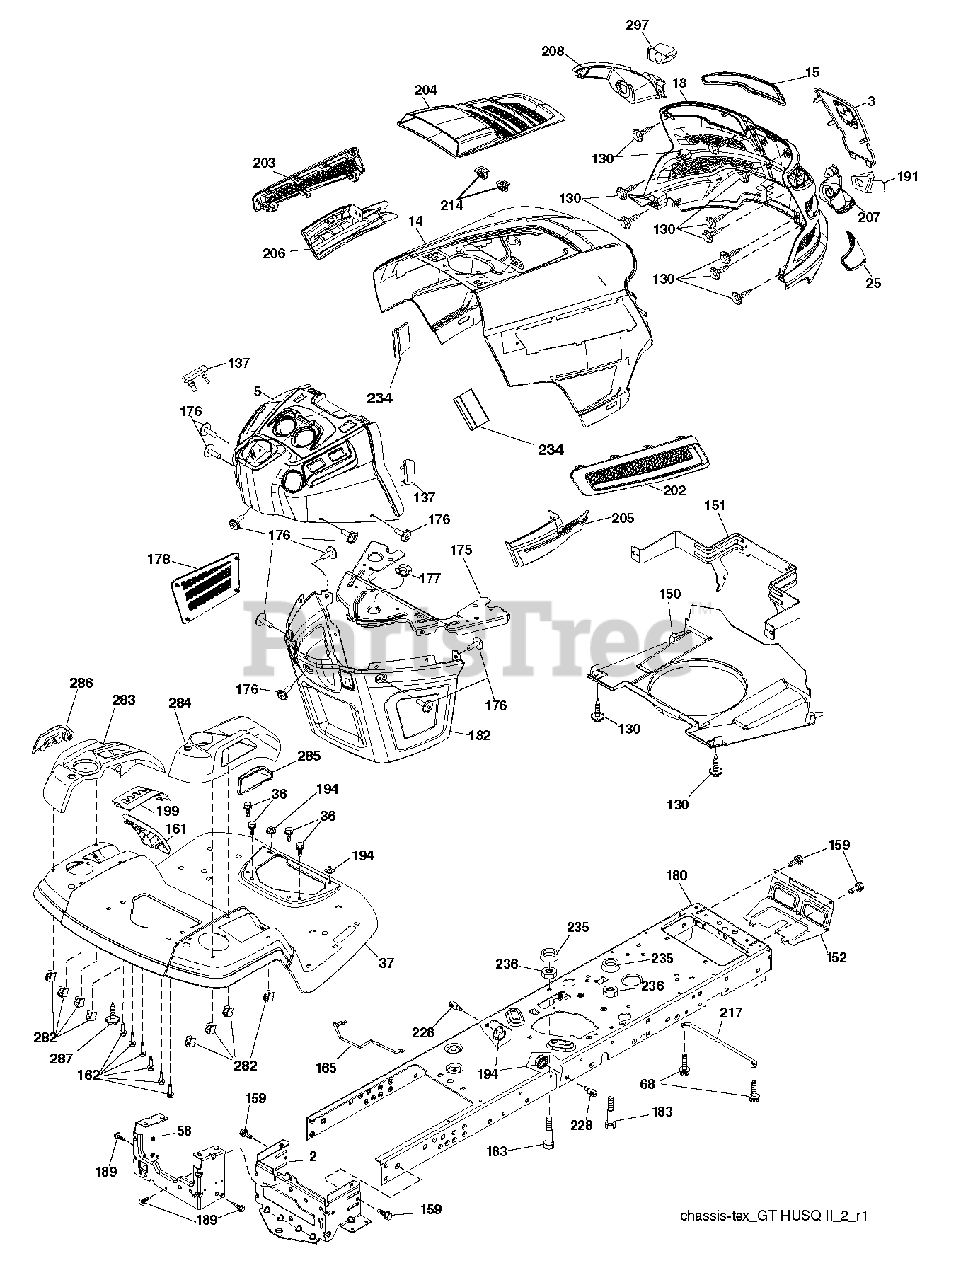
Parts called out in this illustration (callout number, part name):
2	DRAWBAR.1PC.NSTL
3	APPLIQUE.SUBASM.GT.HUSQ.II
5	DASH.UPP.GT2.DUAL.RD.PTO.MCHOK
14	HOOD.ASM.HUSQVARNA.GT.TEX.422
15	LENS.HEADLIGHT.LH.GTII.2011
18	GRILLE.SUBASM.GT.HUSQ.II
25	LENS.HEADLIGHT.RH.GTII.2011
36	SCREW 5/16"
37	FENDER.TLT.FS.W/CPH/FW/RSF.ORN
58	DRAWBAR UPPER 2PC SMALL FENDER
68	SCREW LT
130	SCREW.#10 X 0.750.BOS
137	BUMPER DASH
150	AIR.DUCT.GTV2(2.54"RING HEIGHT
151	BRACKET.PIVOT.HOOD.GT.HUSQ.II
152	SHIELD.BROWNING/DEBRIS
159	SCREW, 3/8-16X3/4
161	WINDOW FUEL
162	SCREW.HI-LO.CONSOLE
165	SUPPORT.TANK.REAR.B/TE
175	PLATE.CROSSMEMBER.HUSQ
176	SCREW.#10-24X5/8.RN.QU
177	BUSHING, STEERING
178	CARGO.ASM.NET.TXGT.W/C
180	CHASSIS.STAMPING.LT/GT
182	DASH.LOWER.COMMON.12V.ADAPTOR
183	BOLT.5/16-18X1-1/4 FULL THD
189	SCREW
191	INSERT.REFLECTIVE.RH.HUSQ.GTII
194	NUT LOCK HEX FLANGE 5/16-18
199	PLATE.DECK.LIFT.HUSQ.LT
202	VENT.SIDE.RH.GT.HUSQ.II.
203	VENT.SIDE.LH.GT.HUSQ.II.498
204	VENT.TOP.HUSQ.GT2
205	SIDE.TRIM.RH.GT.HUSQ.II
206	SIDE.TRIM.LH.GT.HUSQ.II.GRAY
207	BEZEL LIGHT.RH.GT.II.MYLAR
208	BEZEL LIGHT.LH.GT.II.MYLAR
214	CLIP.RETAINER.TINNER.
217	ROD.PIVOT.HOOD
228	STUD.FASTNER.W/ANTI-ROTATE
234	BUMPER.HOOD.TEX.HUSQVARNA
235	SPACER FENDER
236	NUT.CENTERLOCK.5/16-
282	CLIP.RETAINER.CONSOLE.LT.HUSQ
283	CONSOLE.DECK.LFT.R.SDFL.HUSQLT
284	CONSOLE.CNTRL.
285	CONSOLE INSERT RH
286	CONSOLE.INSRT.LH.HUSQ.LT.BLACK
287	SCREW 1/4X20
297	INSERT.REFLECTIVE.LH.HUSQ.GTII
